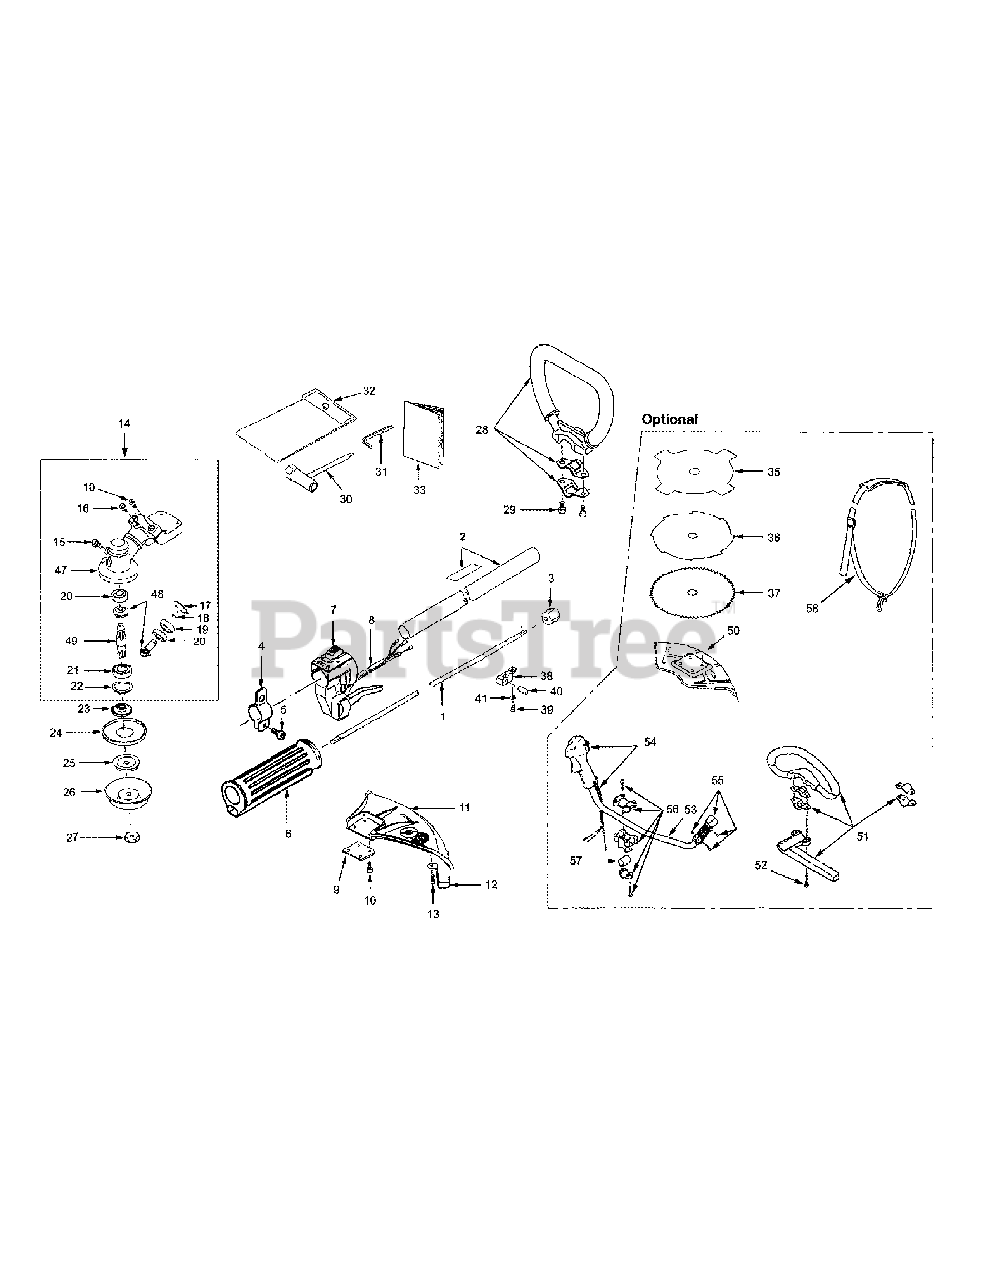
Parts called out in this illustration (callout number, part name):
1	Shaft, Drive
2	Pipe, Complete
7	Lever Assembly, Throttle
8	Wire Complete, Throttle
11	Deflector Assembly, Plastic
14	Case Assembly, Gear
17	Snap Ring, R-24
18	Snap Ring, S-9
19	Bearing, Ball, 609ZZ
20	Bearing, Ball, 609
21	Bearing, Ball, 6001LL
22	Snap Ring, R-28
27	Nut, LH M10x1.25
28	Handle, Loop
30	Wrench, Spanner Box 19
31	Wrench, Key, 4mm
33	Manual, Operator's
35	Blade, 4 Tooth
36	Blade, 8 Tooth
37	Blade, Circular
41	Washer, 5mm
48	Gear Assembly
50	Deflector, Steel
51	Handle Assembly, Loop
54	Lever Assembly, Throttle
55	Grip Assembly
56	Holder Assembly, Handle
58	Harness, Shoulder
